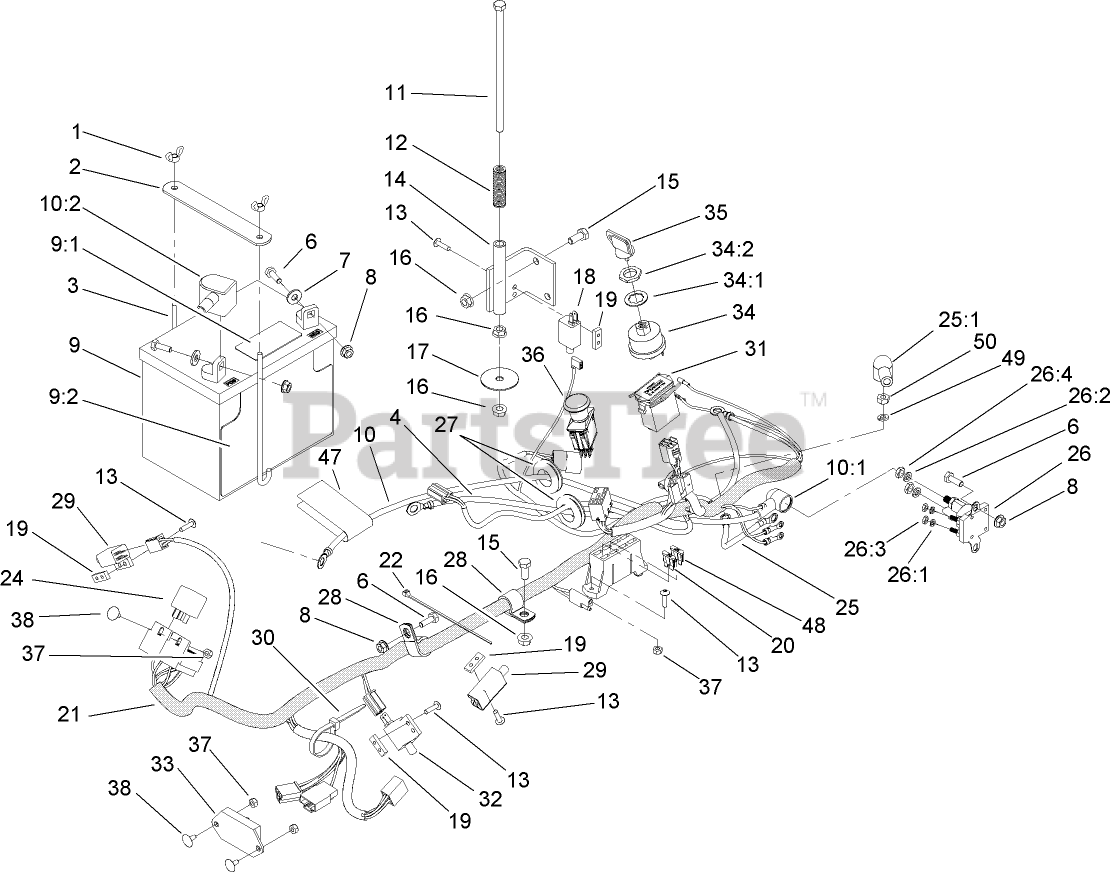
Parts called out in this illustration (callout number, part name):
1	WINGNUT
2	STRAP-HOLDDOWN, BATTERY
3	BOLT-HOLDDOWN
4	CABLE-GROUND, NEGATIVE
6	SCREW-HH
7	WASHER-FLAT
8	NUT-HF
9	BATTERY
9:1	Decal-Battery
9:2	Decal-Battery
10	POSITIVE BATTERY CABLE ASM
10:1	INSULATOR-SOLENOID
10:2	INSULATOR-BATTERY
11	SCREW-HH
12	SPRING-SWITCH, SEAT
13	SCREW-HEAD, TRUSS
14	BRACKET-SWITCH, SEAT
15	SCREW-HH
16	NUT-HF
17	WASHER
18	SWITCH-CLOSED, NORMALLY
19	PLATE-TAPPED
20	FUSE-BLADE, 30 AMP
21	HARNESS-ELECTRICAL
22	TIE-CABLE
25	POSITIVE STARTER CABLE ASM
25:1	INSULATOR-SOLENOID
26	SWITCH-SOLENOID
26:1	WASHER-LOCK
26:2	WASHER-LOCK
26:3	NUT-HEX
26:4	NUT-JAM
27	GROMMET
28	CLIP-LOOM
29	SWITCH-OPEN, NORMALLY
30	TIE-PLASTIC
31	METER-HOUR
32	SWITCH
33	MODULE-DELAY, SEAT
34	SWITCH ASM
34:1	NUT-HH
34:2	WASHER-TOOTH, INTERNAL
35	KEY-IGNITION
36	SWITCH-PTO
37	NUT-LOCK, NI
38	BOLT-CARR
47	DECAL-INSTRUCTIONS, CHARGING
48	FUSE-BLADE, 25 AMP
49	WASHER-LOCK
50	NUT-HEX
